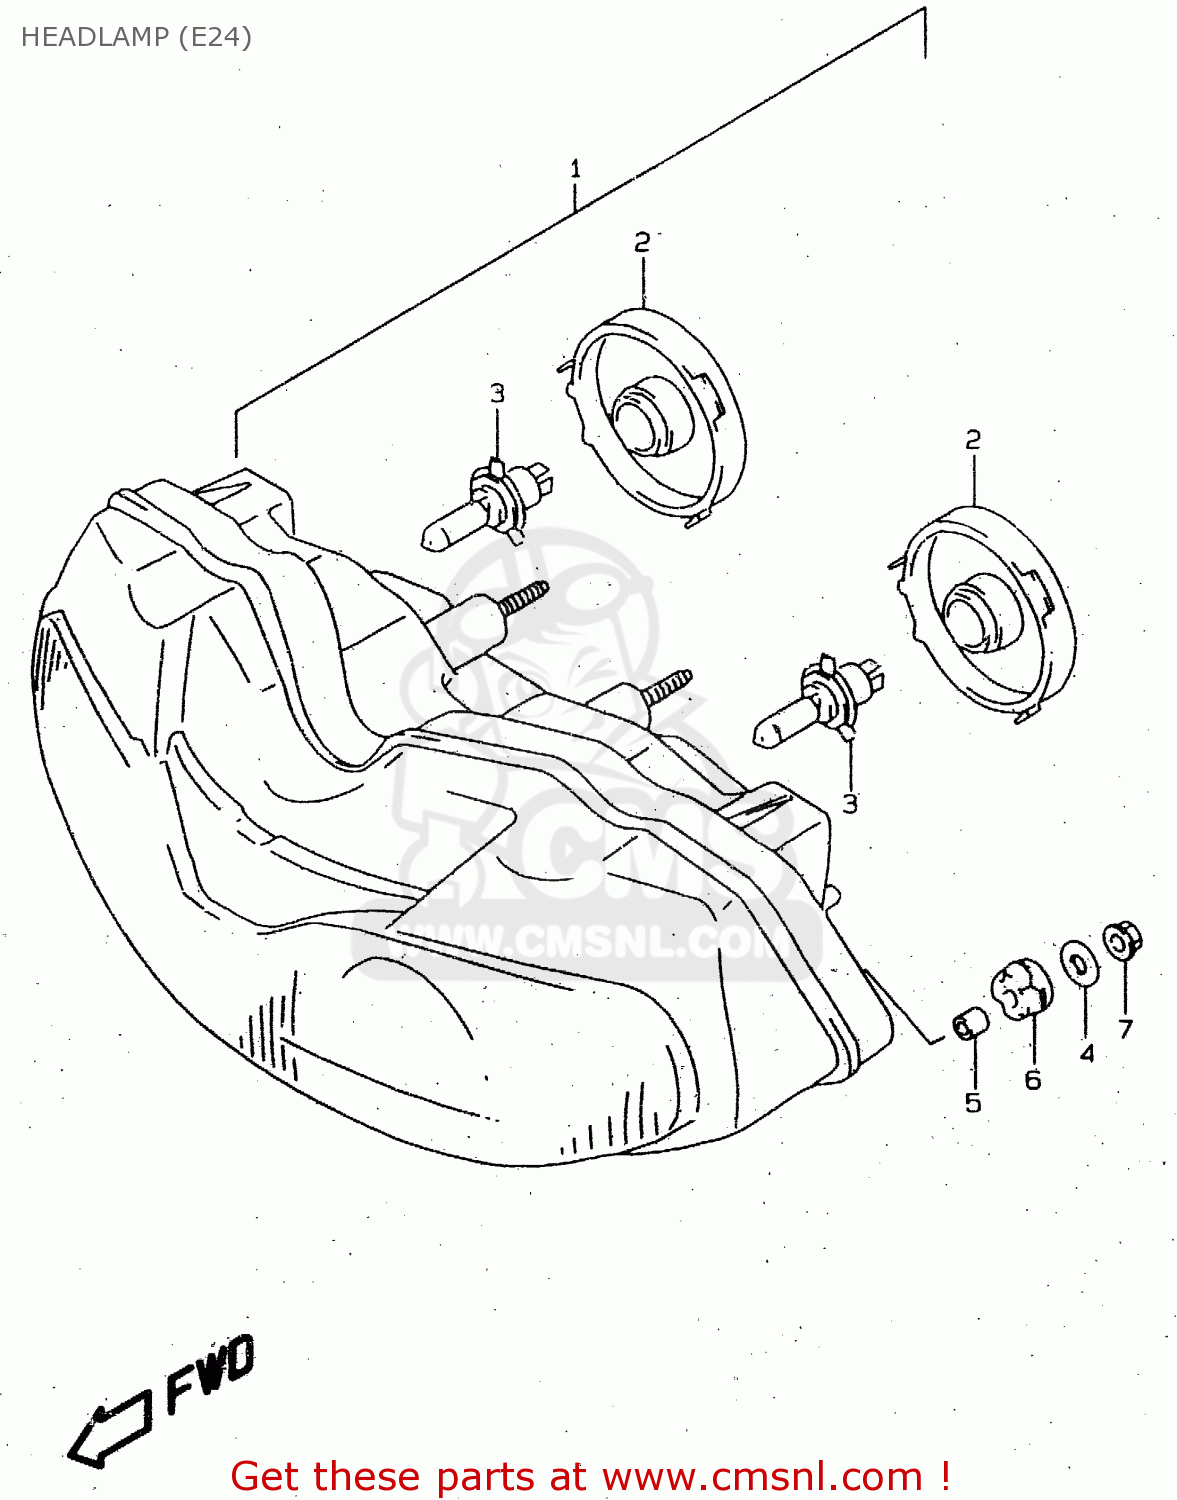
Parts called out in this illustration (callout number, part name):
1	HEADLAMP ASSEMBLY
2	COVER,SOCKET
3	BULB(12V60/55W,H4)
4	WASHER(6.5X20X1.6)
5	SPACER(6.5X9X13.5)
6	CUSHION
7	NUT
